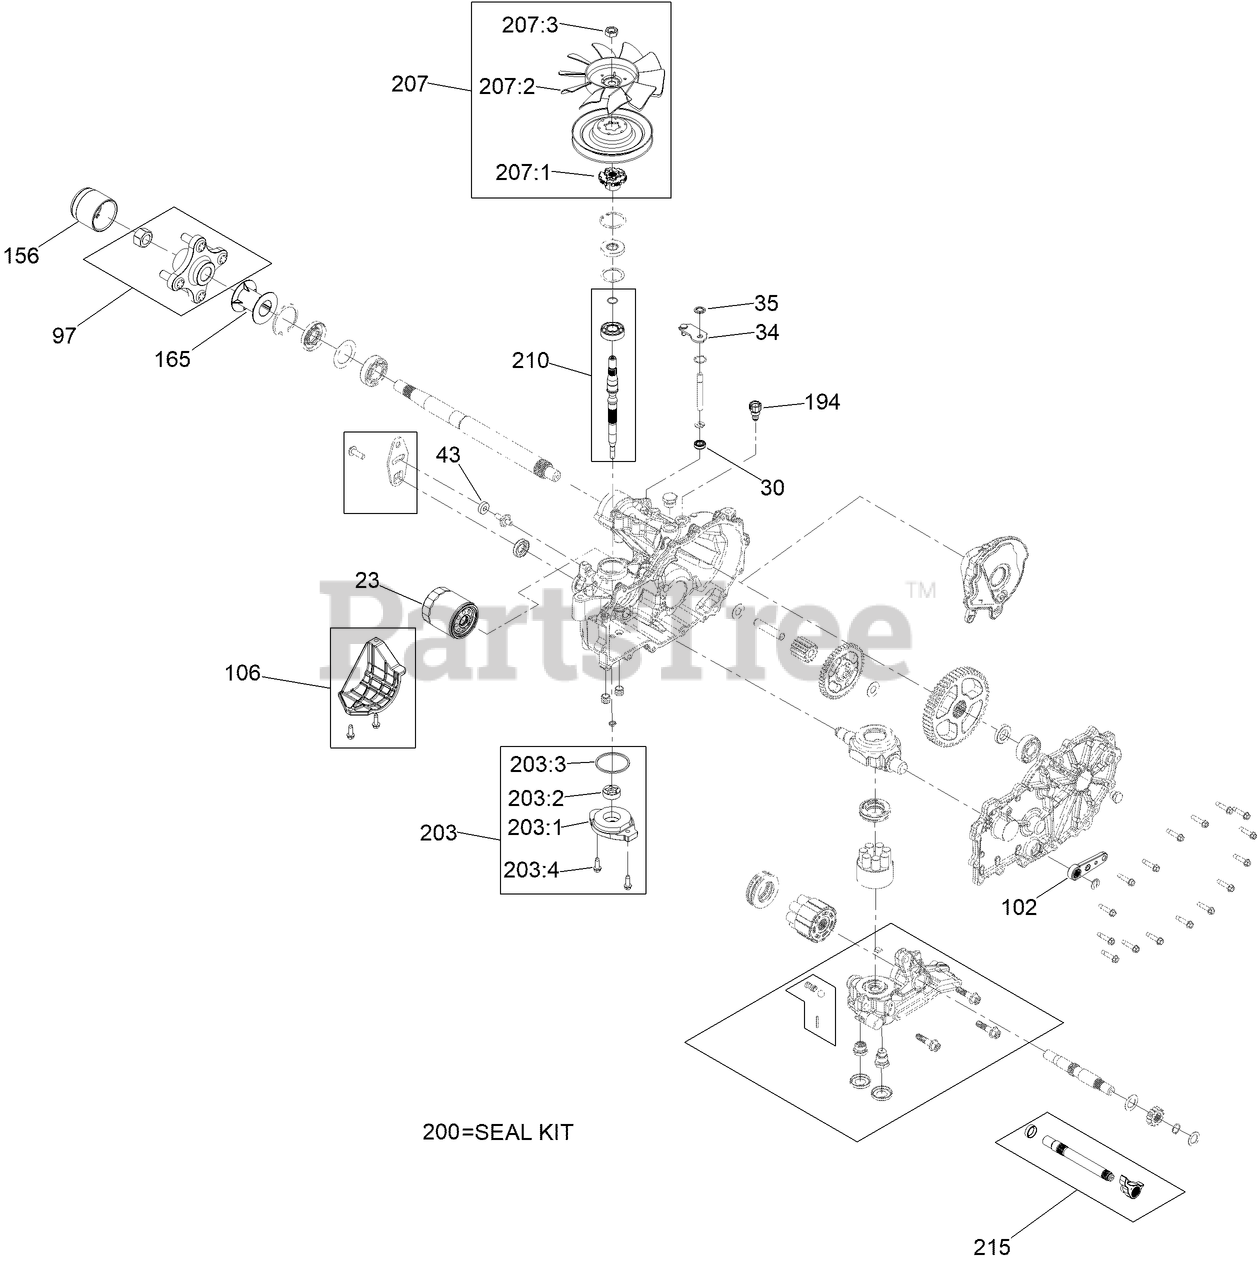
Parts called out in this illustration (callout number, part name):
23	ELEMENT-OIL FILTER, HYD
30	SEAL-LIP
34	ARM-BYPASS
35	RING-RETAINING, EXTERNAL
43	PUCK-FRICTION
97	HUB-OFFSET
102	HANDLE-BRAKE
106	GUARD-FILTER, RH
156	CAP-AXLE, LONG
165	TUBE-AXLE
194	ASSEMBLY-FITTING, BREATHER
200	SEAL KIT
203	CHARGE KIT
203:1	COVER-CHARGE PUMP
203:2	GEROTOR ASM
203:3	O RING-SEAL
207	FAN AND PULLEY KIT
207:1	HUB-FAN
207:3	NUT-HJ
210	INPUT SHAFT KIT
215	INBOARD KIT
